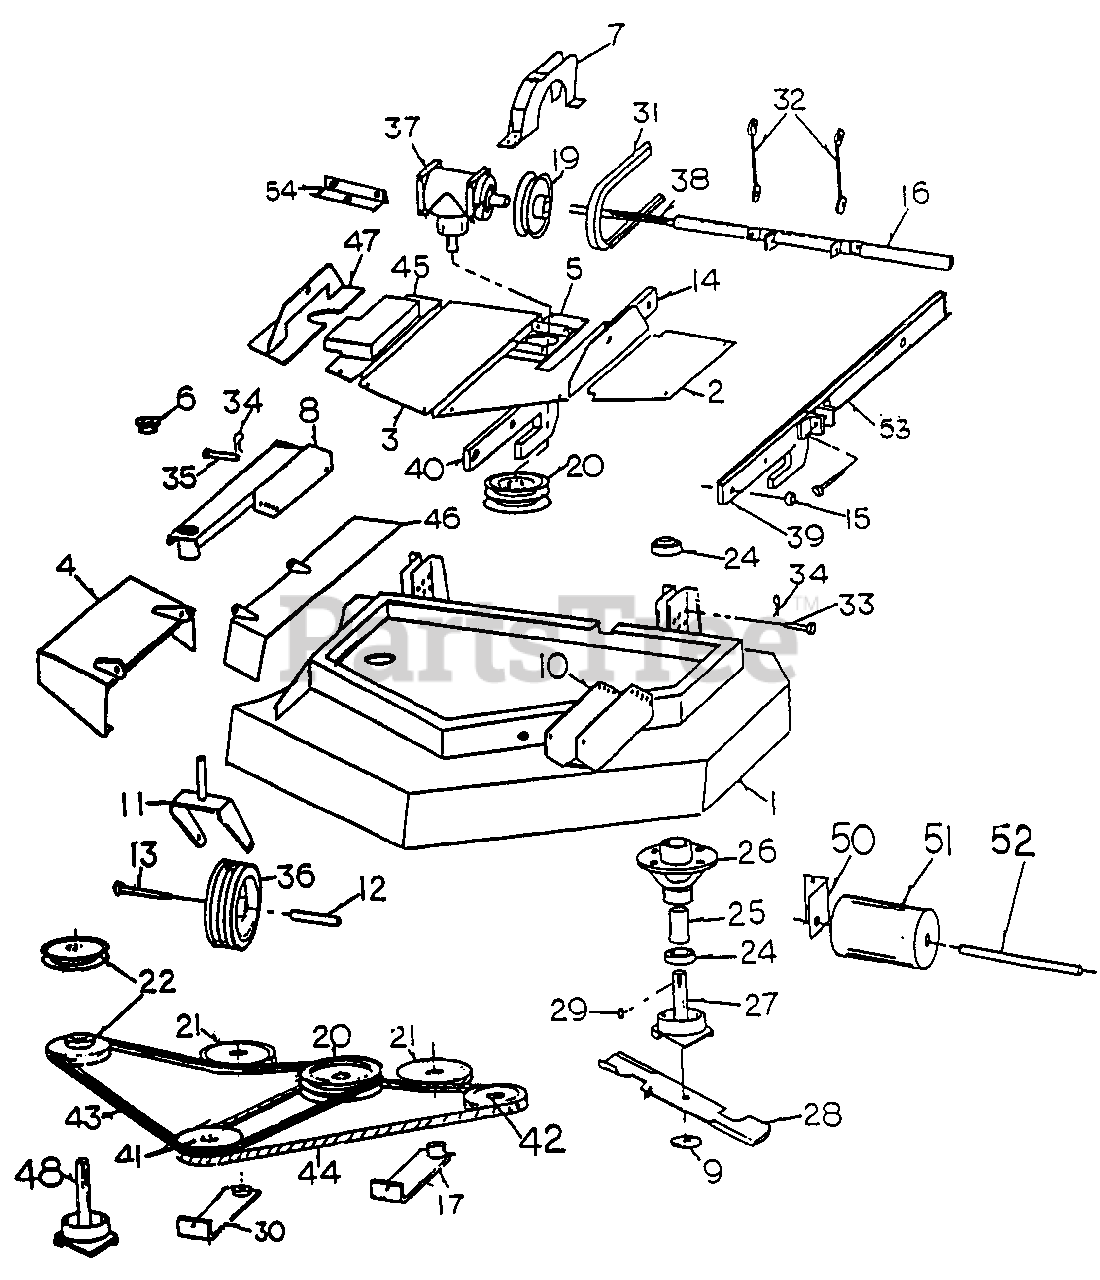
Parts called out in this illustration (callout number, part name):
1	MOWER DECK
3	COVER (LARGE)
5	GEAR BOX MOUNT
6	GACE WHEEL BUSHINC
8	GACE WHEEL MOUNT
10	BRACKET ,GAGE WHEEL MOUNT
11	FORK, GAGE HEEL
12	AXLE, GAGE WHEEL
13	GAGE WHEEL BOLT
14	DECK LIFT ARM BACK ADJUSTABLE
15	BUSHING, DECK LIFT ARM
17	BELT TICHTENER
19	PULLEY, GEAR BOX
20	PULLEY, GEAR BOX
22	PULLEY, SPINDLE
24	BEARING,SPINDLE
25	SPACER, SPINDLE
26	HOUSEING, SPINDLE
27	SHAFT, SPINDLE
29	KEY SPINDLE
30	BELT TIGHTENER
35	PINS, GAGE WHEEL
38	CROSS BAR
39	L.H. DECK LIFT ARM FRONT ADJUSTABLE
40	R.H. DECK LIFT ARM FRONT ADJUSTABLE
41	PULLEY, DOUBLE A
42	PULLEY, LEFT SIDE SPINDLE
43	BELT, DECK LONC
44	BELT, DECK SHORT
46	FOOT GUARD MOUNT
47	DECK MOUNT
48	SHAFT, SPINDLE LONG
50	ROLLAR BRACKET
53	L.H. DECK LIFT ARM BACK ADJUSTABLE
54	GEAR BOX MOUNT ANGLE
